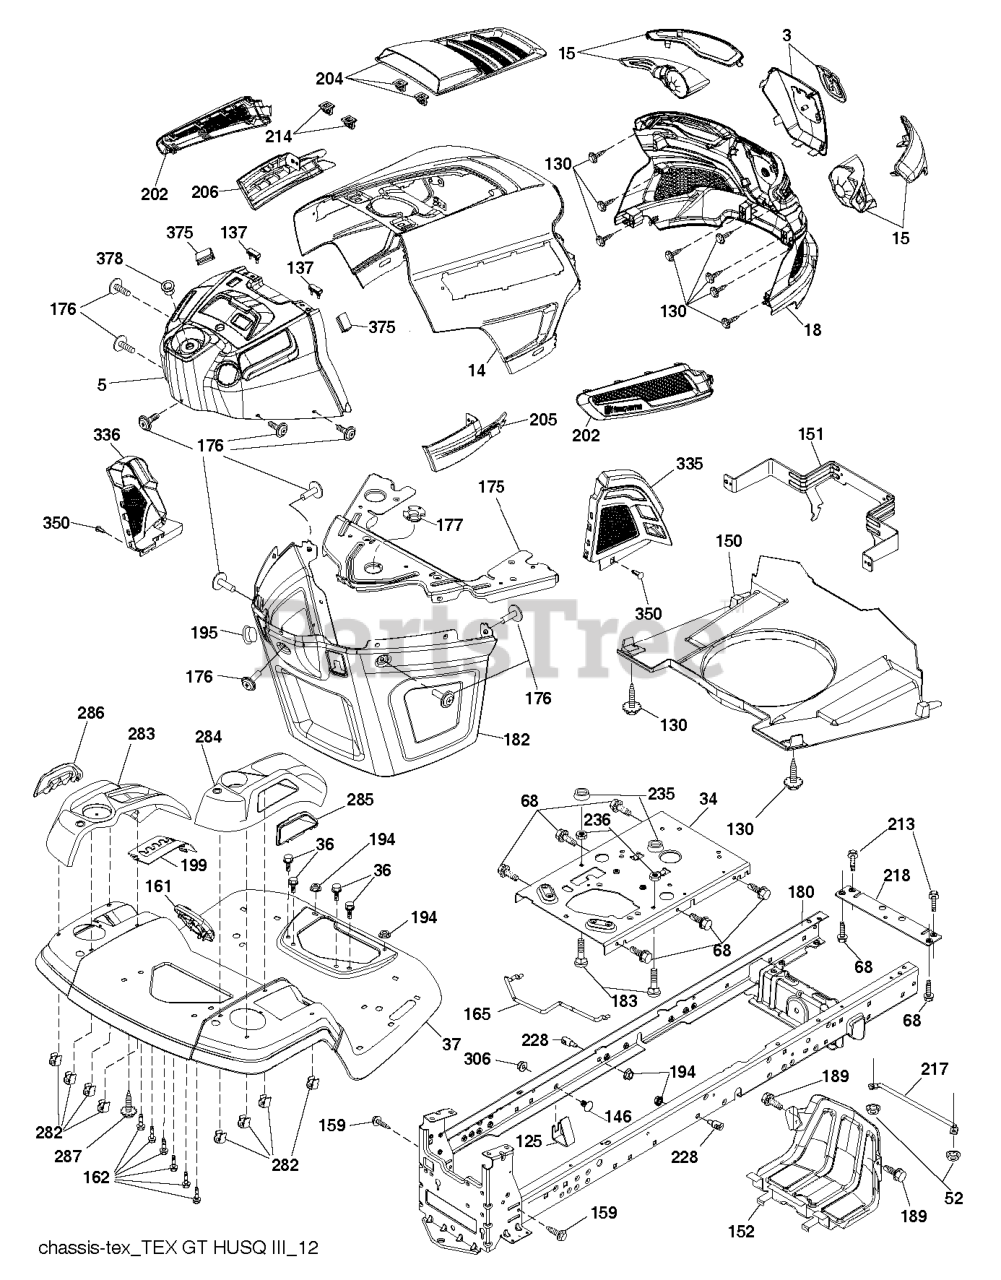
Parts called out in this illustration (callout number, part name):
5	DASH.ASM.W/BUMPERS.READYSTART
14	HOOD.ASM.HUSQVARNA.GT.TEX.ORAN
15	Service Kit
34	PLATE.ENGINE.WELDED.CHASSIS
36	SCREW 5/16"
37	FENDER.TLT.FS.W/CPH/FW/RSF.668
125	CLIP.FUEL.LINE
137	BUMPER DASH
146	BOLT.RDHD.SHT.SQNK.3/8-16X5/8
150	AIR.DUCT.GTV2(2.54"RING HEIGHT
151	BRACKET.PIVOT.HOOD.GT.HUSQ.II
152	SHIELD.BROWNING.PNT.GT.V2
159	SCREW, 3/8-16X3/4
161	WINDOW.FUEL.LT.HUSQ.TEX.498
165	SUPPORT.TANK.REAR.W/TEX
175	PLATE.PNT.CROSSMEMBER.HUSQ/PRE
176	SCREW.#10-24X5/8.RN.QU
177	BUSHING STEERING
180	CHASSIS
182	DASH.LOWER.COMMON.12V.ADAPTOR
189	SCREW
195	PLUG.HOLE.DASH.LOWER.12V.BLK
199	PLATE.DECK.LIFT.HUSQ.LT
202	Vents
205	SIDE.TRIM.RH.GT.HUSQ.II
206	SIDE.TRIM.LH.GT.HUSQ.II.GRAY
213	SCREW HEXAGON HEAD SCREW 5/16-
214	CLIP.RETAINER.TINNER.
217	ROD.PIVOT.HOOD
218	X-PIECE.HOOD.STOP.NON/
228	STUD.FASTNER.W/ANTI-ROTATE
236	NUT.CENTERLOCK.5/16-
282	CLIP.RETAINER.CONSOLE.LT.HUSQ
283	CONCOLE.CNTRL.PDL.HUSQ.LT.498
284	CONSOLE.DECK.LIFT.R.SDFL.HUSQ
285	CONSOLE INSERT RH
286	CONSOLE.INSRT.LH.HUSQ.LT.BLACK
287	SCREW 1/4X20
306	NUT LOCK FLG 3/8-16 UNC
335	COVER.LOWER.DASH.RH.BLACK
336	COVER-LH.LOWER.DASH.GT2.BLACK
350	CLIP.X-MAS.TREE
375	BUMPER CLIP-ON. DASH 1"
378	BUSHING FLANGE; PLASTIC
